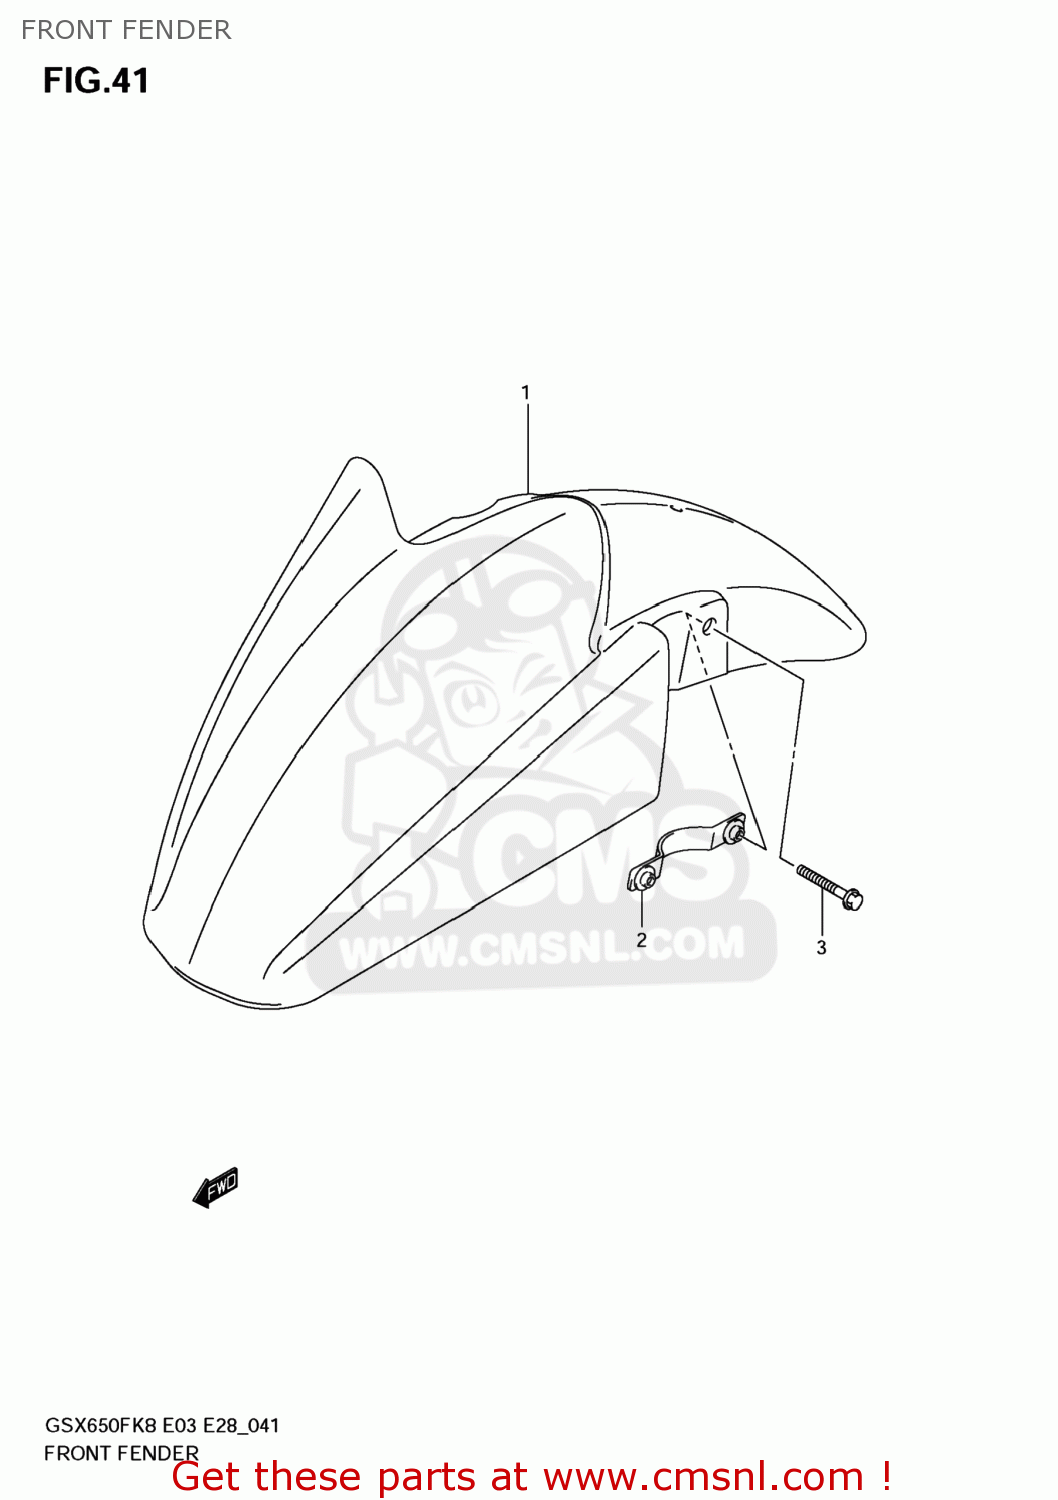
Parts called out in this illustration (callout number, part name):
1	FENDER,FR
2	PLATE,FR FENDER
3	BOLT(6X35)
